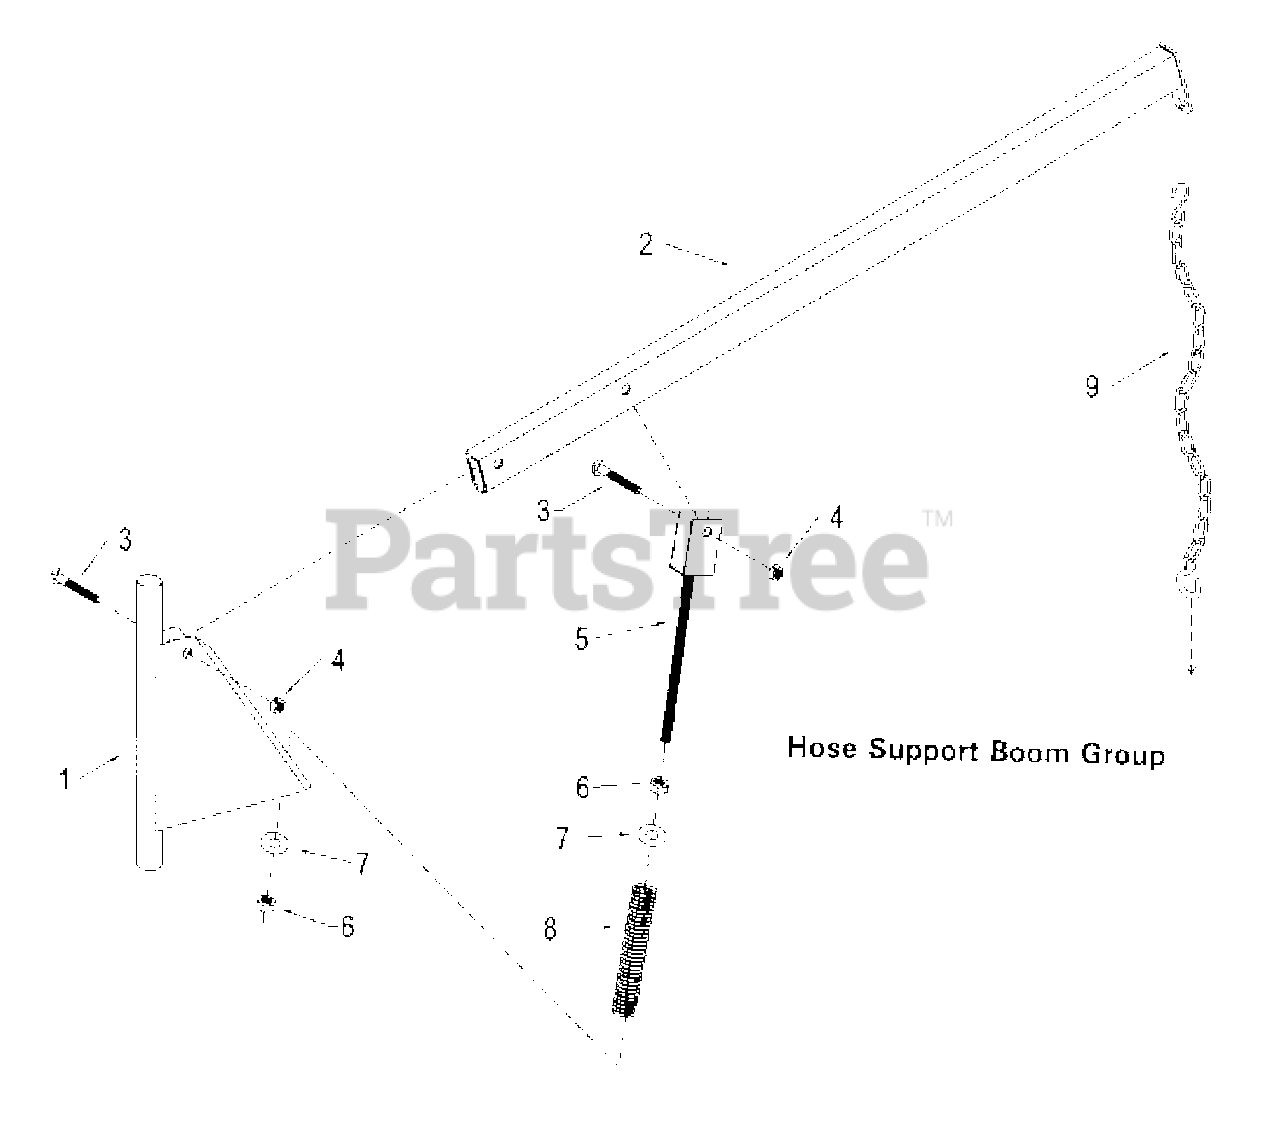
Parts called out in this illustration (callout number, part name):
1	Boom Vertical Member
2	Boom Horizontal Member
3	1/2-13 x 3 Hex Bolt
4	1/2-13 Lock Nut
5	Guide, Threaded Spring
6	3/4-10 Hex Nut
7	3/4 Flat Washer
8	Spring, Boom
9	Chain, Boom w/2 S-Hooks
